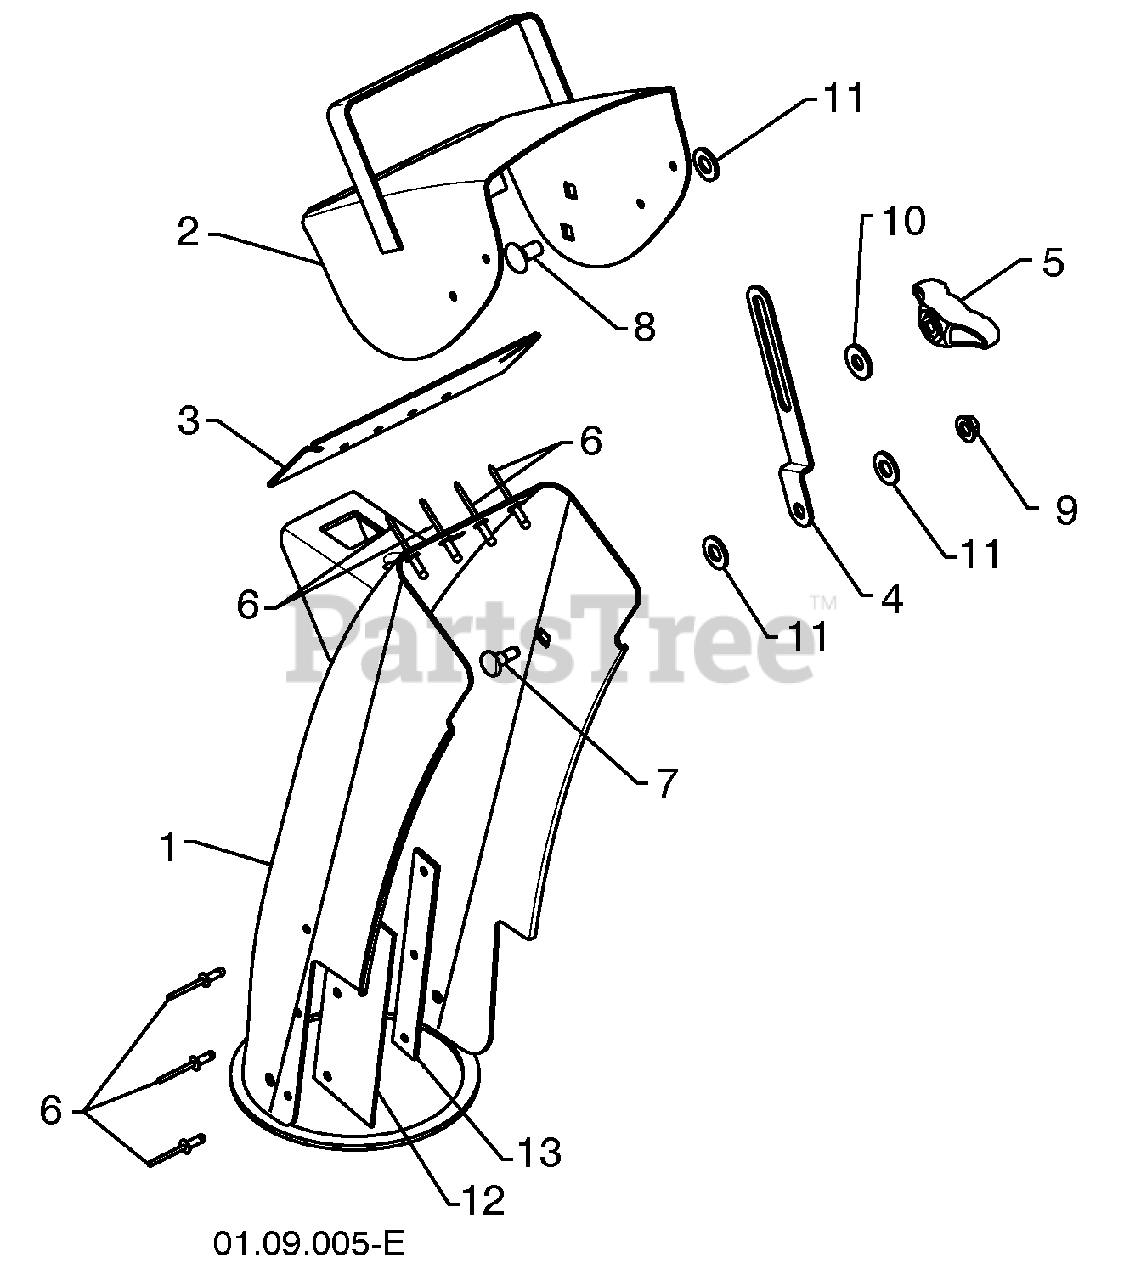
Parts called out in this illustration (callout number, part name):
1	CHUTE WELDMENT
2	DEFLECTOR WELDMENT
3	DEFLECTOR SEAL
4	STRAP
5	KNOB BLACK
6	POP RIVET
7	SHOULDER BOLT 1/4-20 X .704
8	CARRIAGE BOLT 5/16-18 X .625
9	NUT 1/4-20
10	WASHER
11	PLASTIC WASHER
12	CHUTE SNOW SHIELD
13	SHIELD RETAINER STRAP
